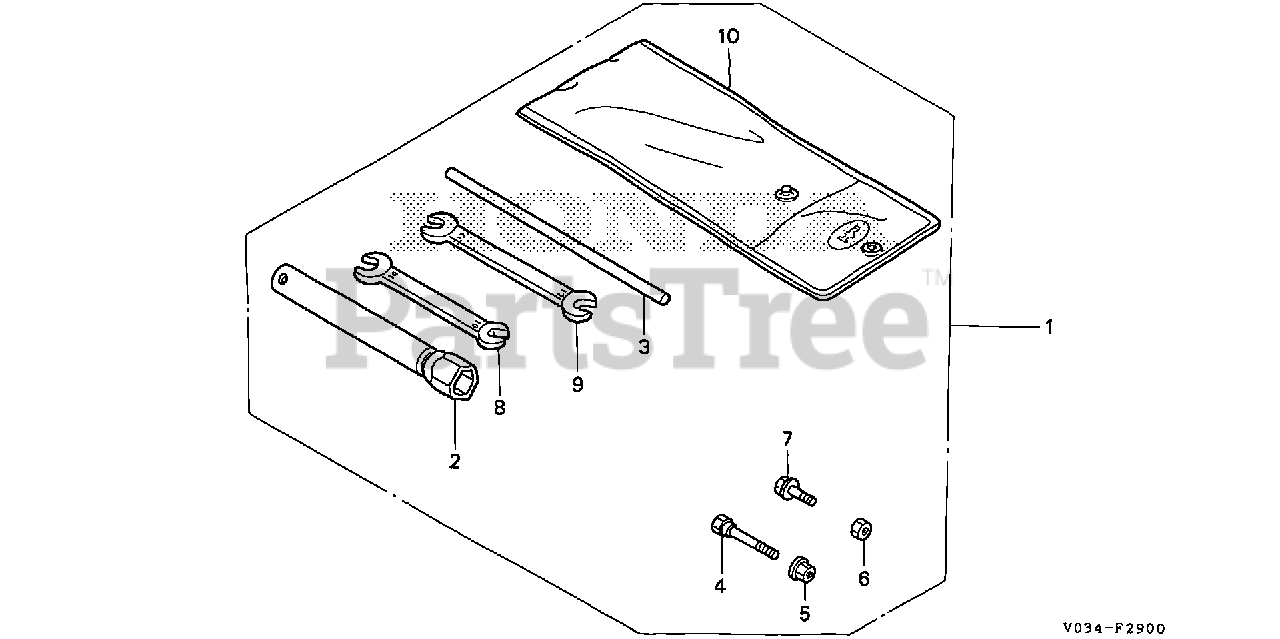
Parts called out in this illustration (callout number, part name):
1	TOOL KIT
1	TOOL KIT (NOT AVAILABLE)
2	WRENCH, SPARK PLUG
3	HANDLE, BOX WRENCH
4	BOLT, LOCK
5	NUT, SELF-LOCK (6MM)
6	NUT, HEX. (6MM)
7	BOLT, HEX. (6X16)
7	BOLT, FLANGE (6X16)
8	SPANNER (10X14)
9	SPANNER (12X17)
